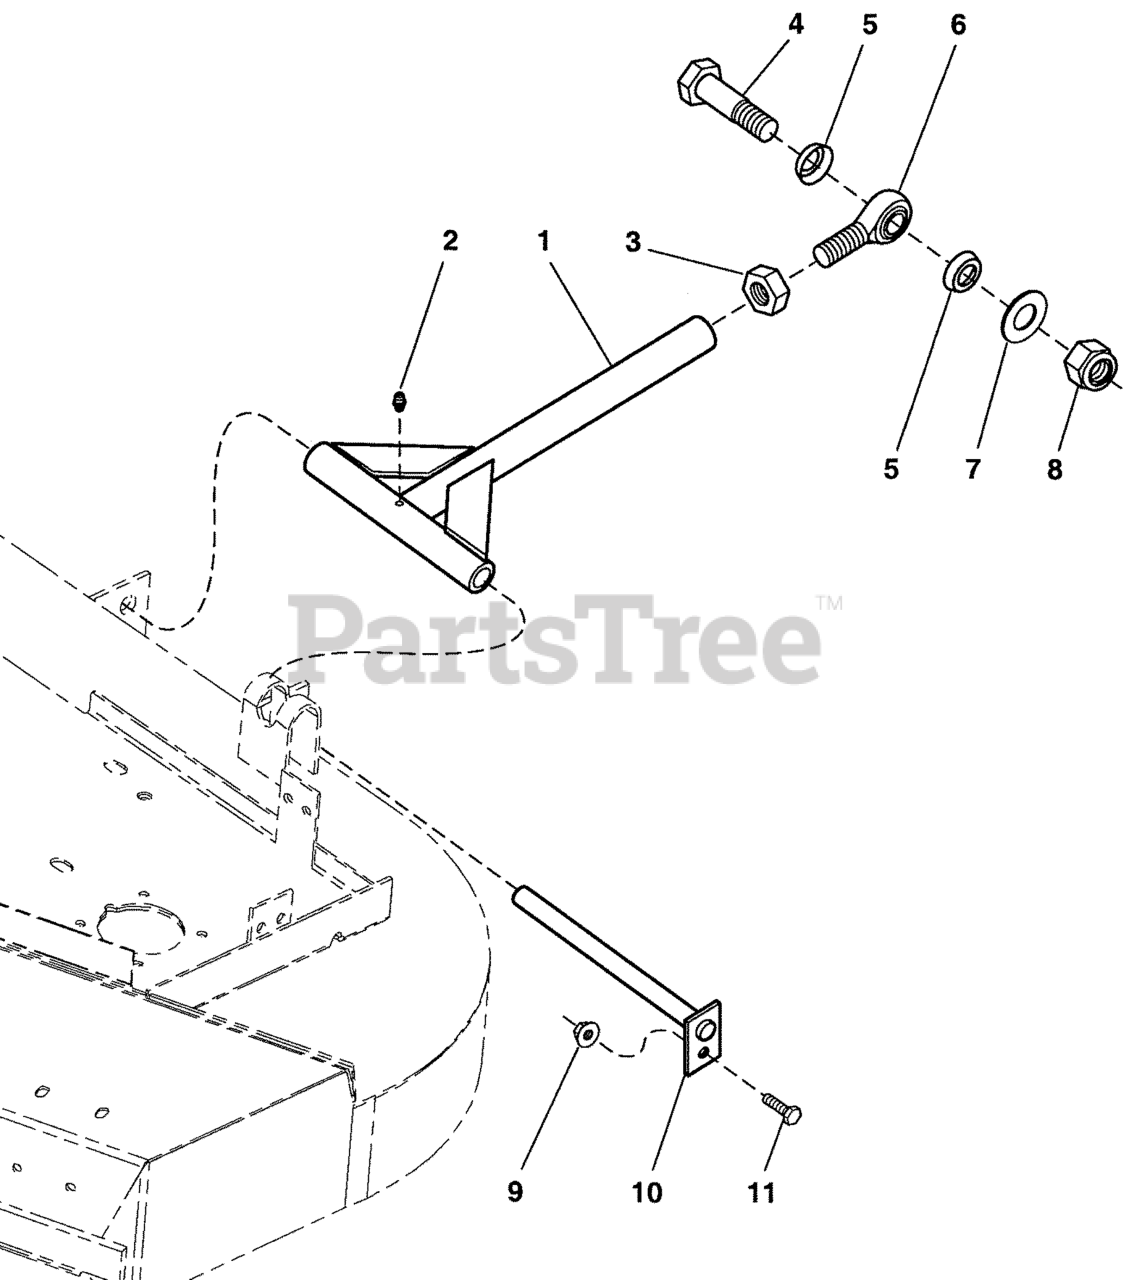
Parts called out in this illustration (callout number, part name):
1	DECK PUSHER BAR
2	GREASE FITTING
3	NUT, Hex, Jam, 3/4-16
4	BOLT, 3/4-16 x 3
5	ROD END SEAL
6	BALL JOINT, 3/4-16
7	WASHER, 3/4 SAE
8	NUT, Hex, Nylon Lock, 3/4-16
9	NUT, 5/16-18 HEX SERRATED FLANGE (LARGE)
11	BOLT, 5/16-18 X 1 GD5 YZ
